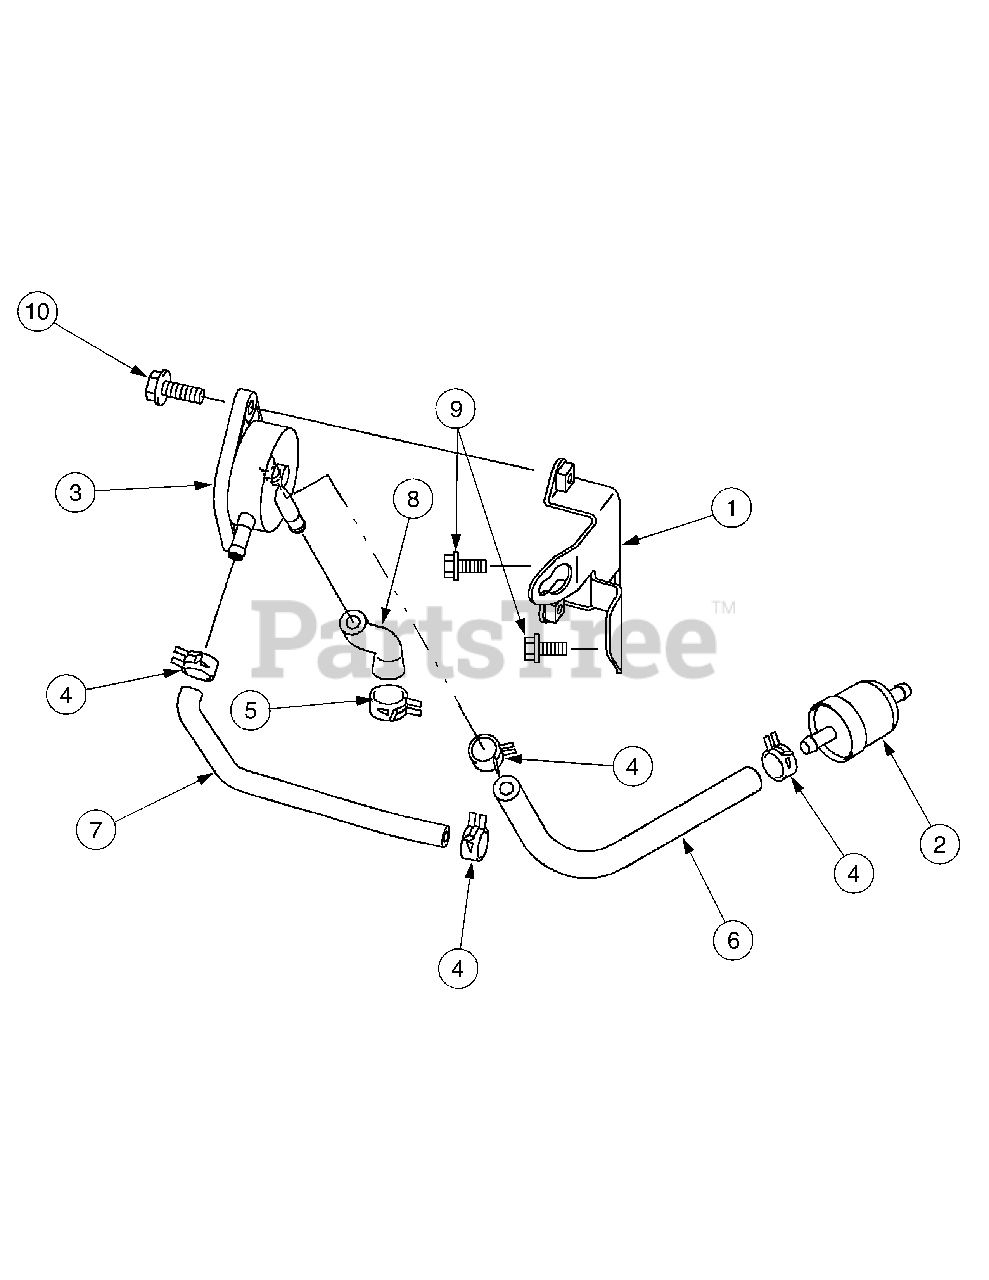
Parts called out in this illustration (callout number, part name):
1	Bracket
2	Filter, Fuel
3	Pump, Fuel
4	Clamp
6	Tube. 6.35 x 12.7 x 160
9	Bolt, Flanged
12	Bolt, Flanged
